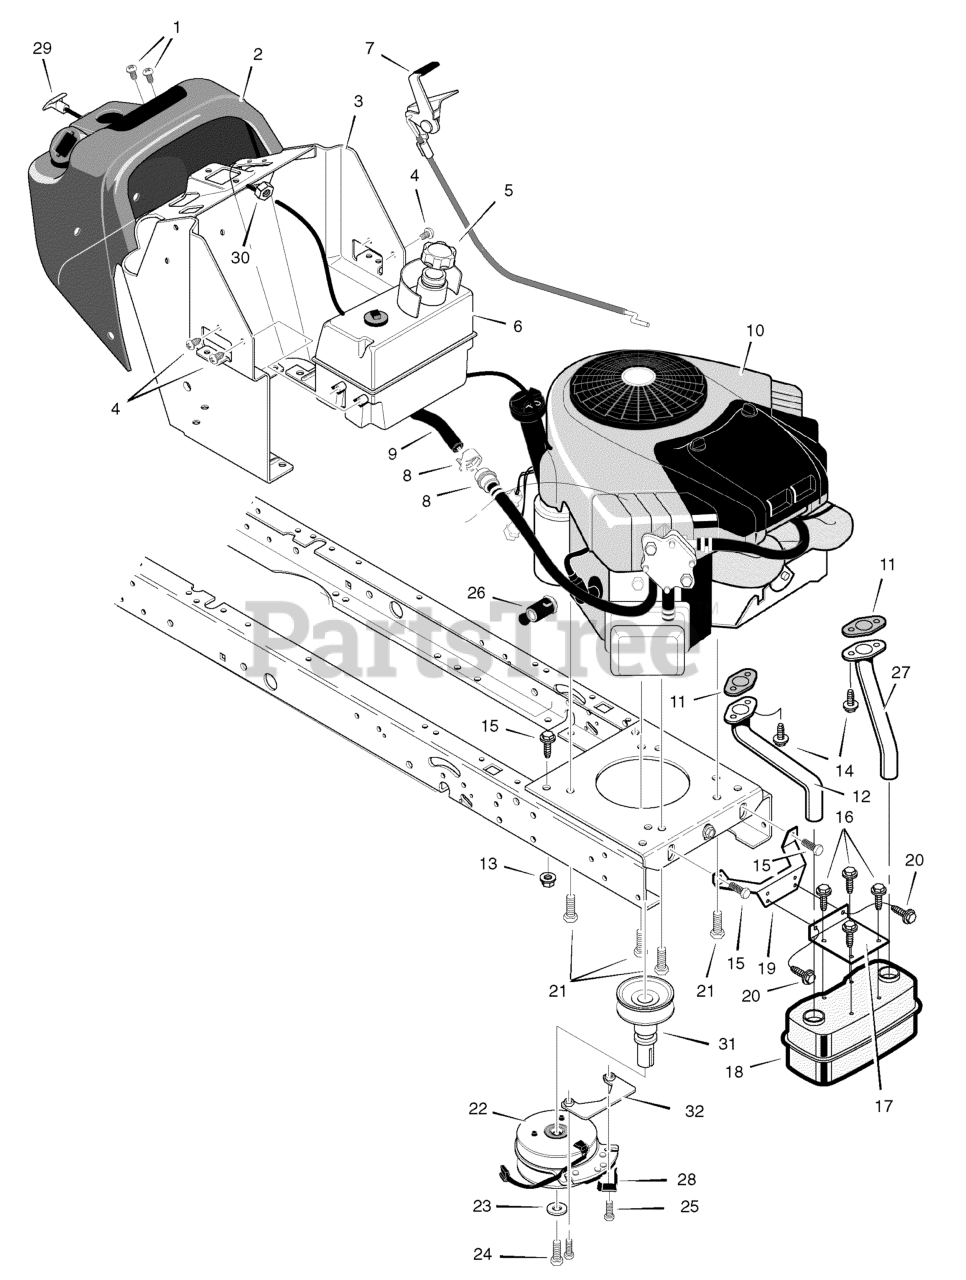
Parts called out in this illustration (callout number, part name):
1	Screw
3	Console
5	Cap, Fuel
6	Tank, Fuel
7	Control, Throttle
8	Clamp, Hose
9	Line, Fuel (Must cut to length)
10	Engine
11	Gasket, Exhaust
12	Tube, Right Exhaust
13	Nut
14	Bolt
15	Screw
16	Screw
17	Bracket, Muffler
18	Muffler
19	Bracket, Muffler Mount
21	Bolt, Engine Mount
22	Clutch, Electric
23	Washer
25	Screw
26	Drain, Oil
27	Tube, Left Exhaust
28	Guide, Belt
30	Nut
31	Adapter, Pulley
32	Plate, Brake
